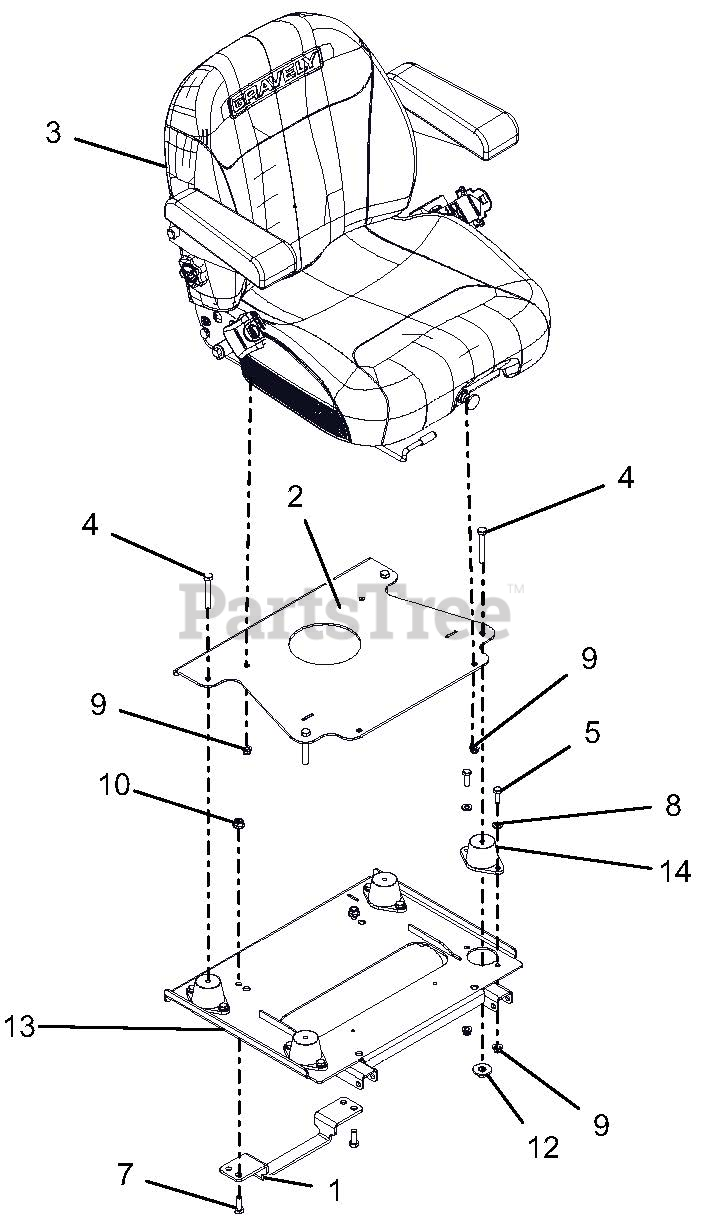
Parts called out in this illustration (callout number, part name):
1	BRACKET - SEAT LATCH
2	WMT, SEAT PLATE
3	SEAT, AIR SUSPENSION
4	BLT-HEX .38-16X2.50 FTH YWZC
5	@BLT-HEX .31-18X1.00 GR5 YWZC
7	@BLT-HEX .38-16X1.00 GR5 YWZC
8	@WSHR-FL-STL.344X.688X.065YWZC
9	@NUT-LK-NYL-FLG .31-18 YWZC
10	@NUT-LK-NYL-FLG .38-16 YWZC
12	WLDMT, SEAT RETAINER
13	SEAT ISO MTG WMT W/SFTY DECAL
14	MOUNT, ISOLATOR
